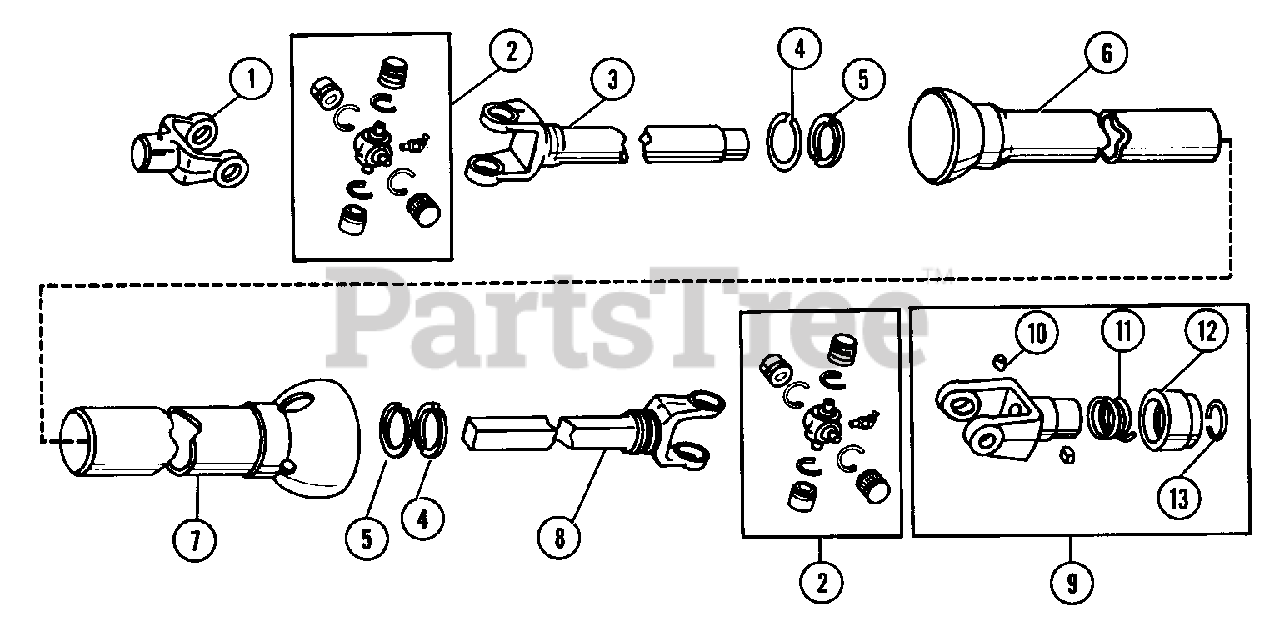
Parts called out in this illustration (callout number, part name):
1	END YOKE
2	REPAIR KIT
3	YOKE AND TUBE
4	RG-RTNG WEASLER #2A N20
5	BRG-BALL NYL WEASLER
6	MALE GUARD TUBE
7	FEMALE GUARD TUBE W/DECAL
8	YOKE AND SHAFT
9	LOCK YOKE ASSEMBLY
10	STAINLESS BALL
11	SG ??X??X?? WEASLER
13	RG-RTNG
14	CAUTION DECAL
